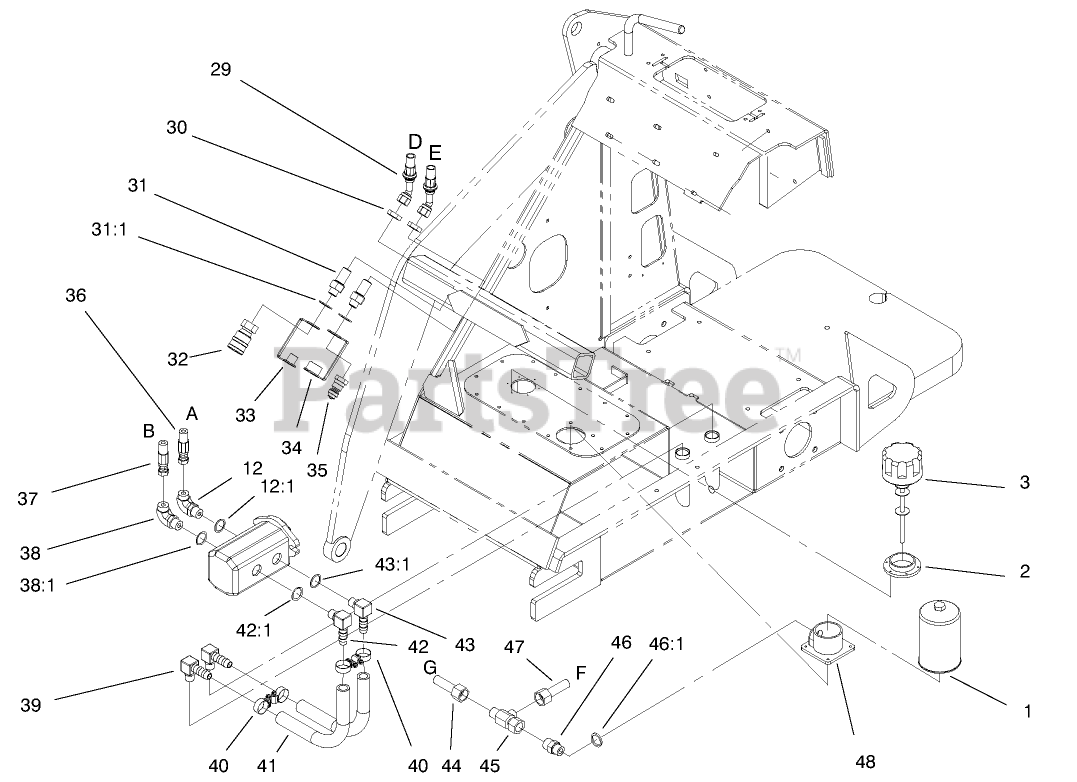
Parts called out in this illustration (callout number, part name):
1	FILTER-ELEMENT
2	Cap-Mount
3	CAP-HYD
12	ADAPTER
12:1	O-RING
29	HOSE-HYD
30	NUT-BULKHEAD
31	UNION-BULKHEAD
31:1	O-RING
32	QUICK COUPLER-FEMALE
33	Dust Plug
34	Cap-Dust
35	QUICK COUPLER - MALE
36	HOSE-HYD
37	HOSE-HYD
38	ADAPTOR - 90 DEG
38:1	O-RING
39	FITTING-BARBED 90 DEG
40	CLAMP-HOSE
41	HOSE - HYD
42	FITTING-BARBED 90 DEG
42:1	O-RING
43	FITTING-BARBED 90 DEG
43:1	O-RING
44	TUBE-HYD
45	FITTING-TEE
46	FITTING-STRAIGHT
46:1	O-RING
47	TUBE-HYD
48	FILTER-MOUNT
